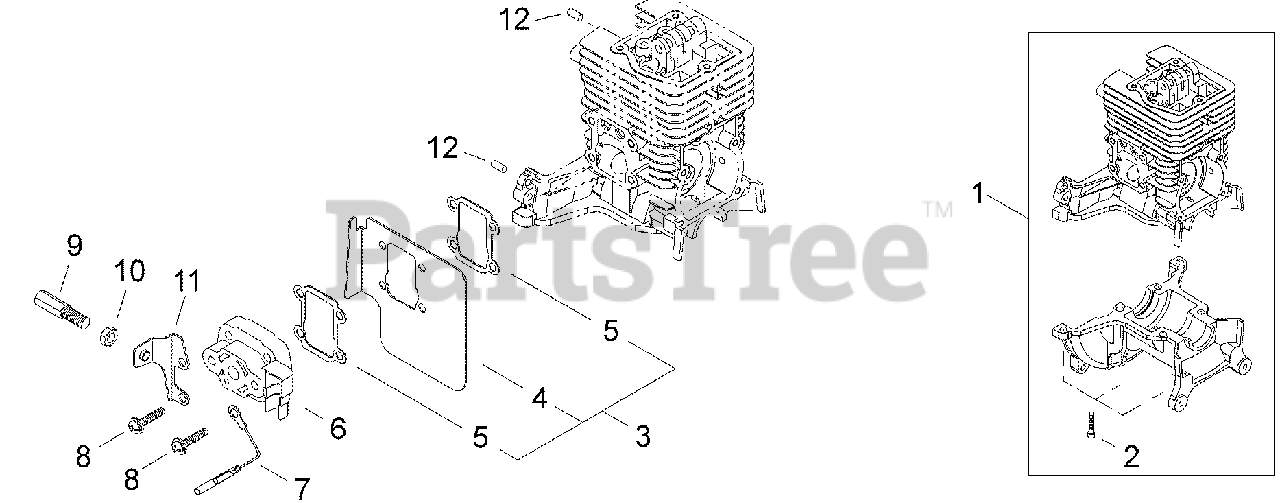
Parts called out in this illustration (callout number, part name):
1	CYLINDER & CRANKCASE ASSY
2	BOLT 5×16
3	SHIELD ASSY, INTAKE HEAT
4	HEAT SHIELD, INTAKE
5	GASKET, EXHAUST
6	INSULATOR WITH REED VALVE
7	LEAD - GROUND L= 110 MM
8	SCREW M5×22
9	ADJUSTER, THROTTLE CABLE
10	NUT, ADJUSTER LOCK M6
11	BRACKET, THROTTLE CABLE
12	PIN, LOCATING Ø4×8
